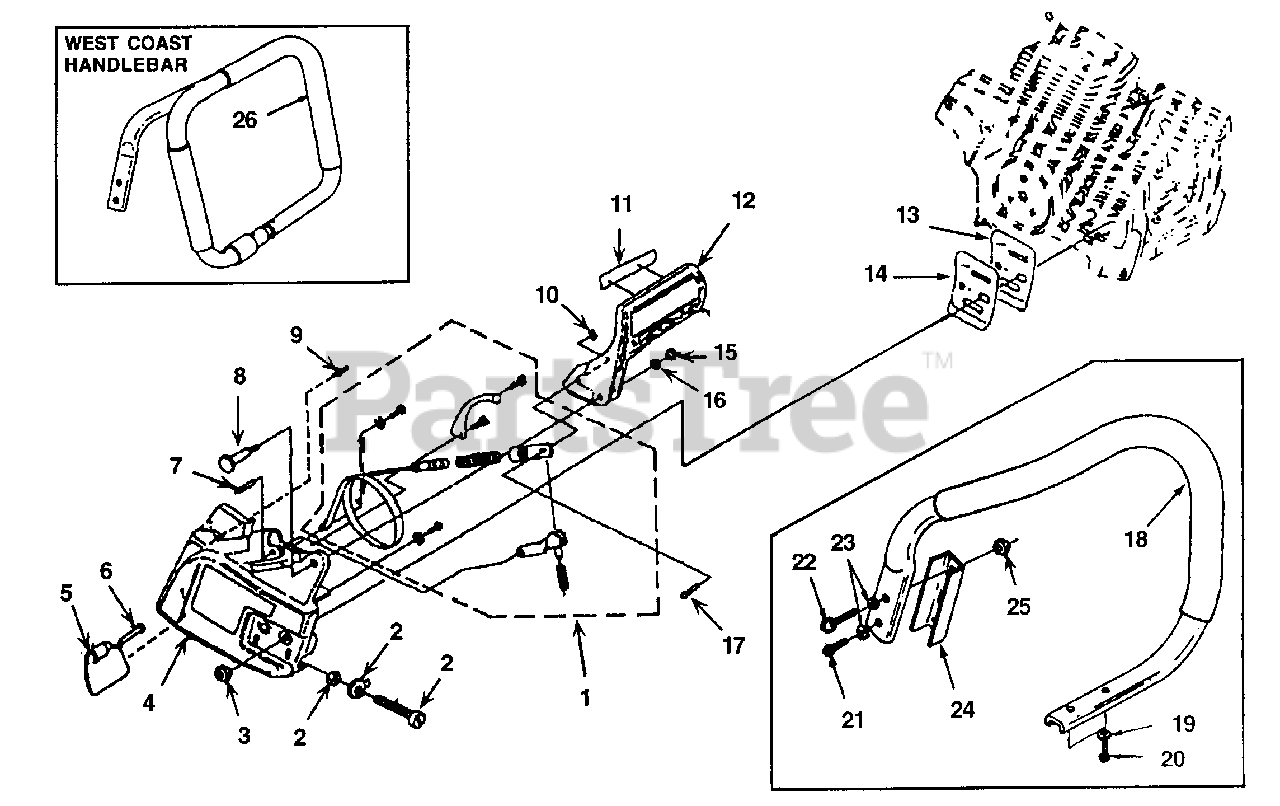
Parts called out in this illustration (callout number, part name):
1	BRAKE BAND ASSY
2	GUIDE BAR ADJ. KIT
3	NUT - HEX (10-24)
4	COVER - DRIVE CASE
5	SAWDUST SHIELD
6	RIVET - PAN HD (.187 X .381)
7	PIN (5M X 16MM)
8	SCREW - SHOULDER (MS)
9	PIN - SHOULDER DOWEL
10	RING - SNAP
11	DECAL HANDGUARD
12	HANDGUARD
13	PLATE - G/BAR (INNER)
14	PLATE - G/BAR (OUTER)
15	NUT (5MM)
16	WASHER - BELLEVILLE (12MM)
17	PIN - (.156 DIA)
18	HANDLE BAR (Flush Cut)
19	WASHER - Conical (#10)
20	SCREW - Socket Cap (10-32 X 5/8")
21	SCREW - Socket Cap (10-24 X 3/4")
22	SCREW - Socket Cap (10-32 X 7/8")
23	WASHER - Conical (#10)
24	NEST KIT
25	NUT - Lock (#10)
26	HANDLE BAR (West Coast)
